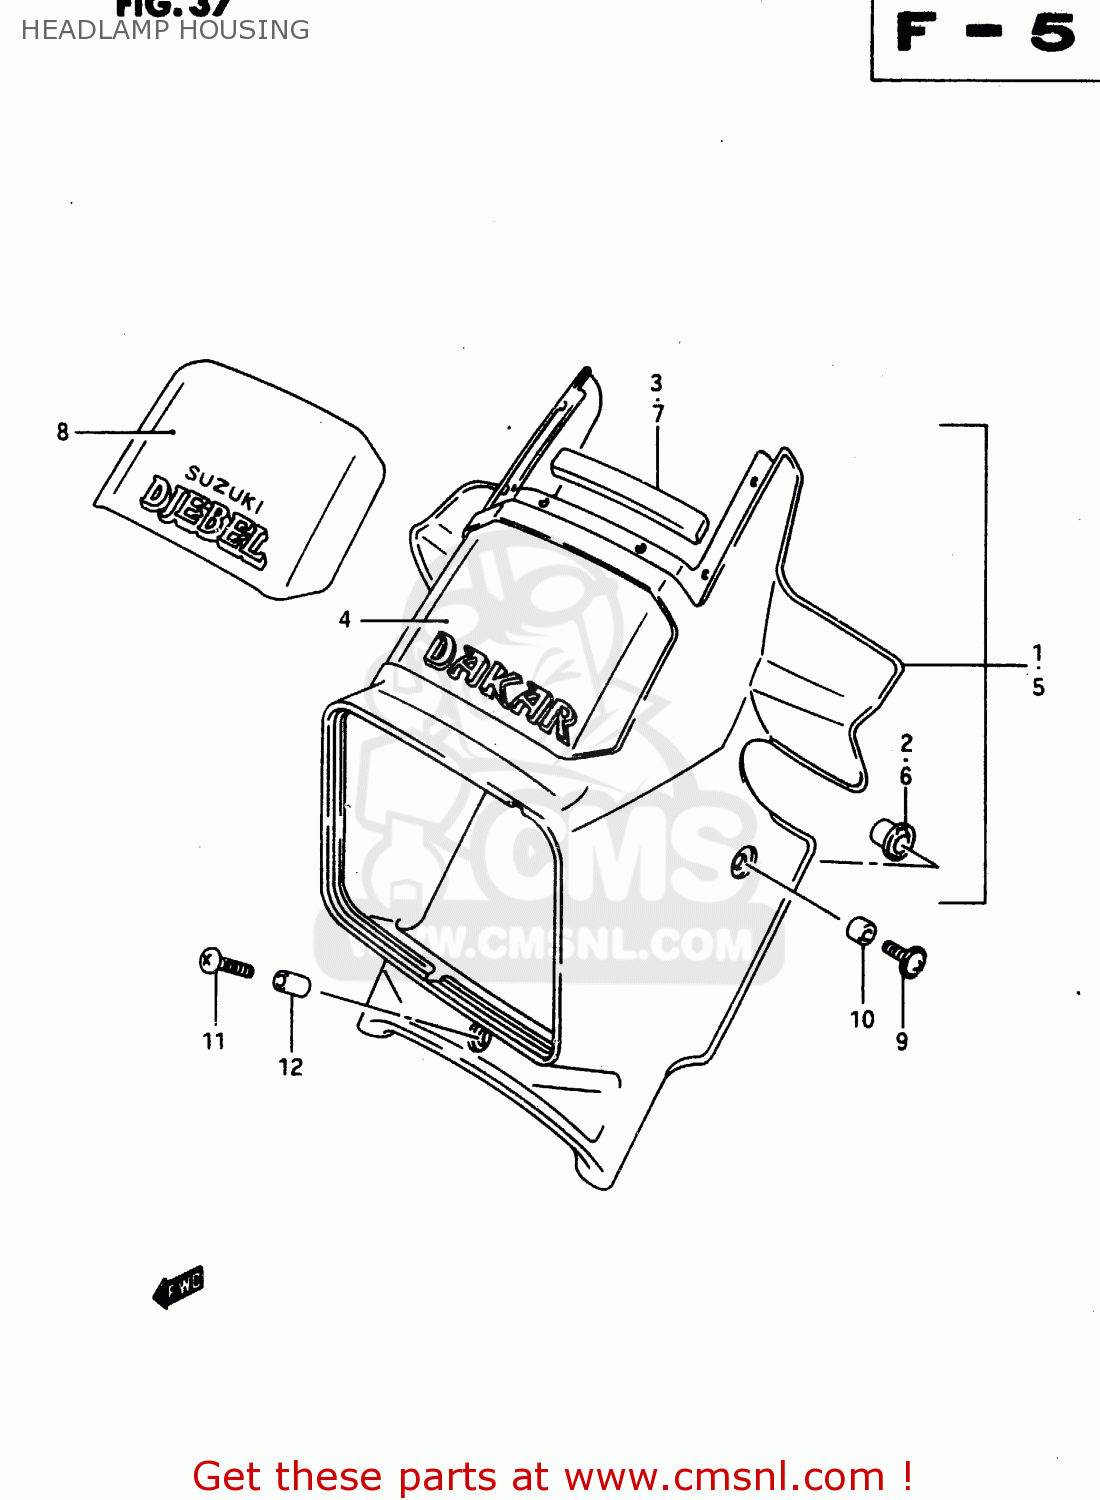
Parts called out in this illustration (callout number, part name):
1	COVER, HEADLAMP (WHITE)
2	BUSH, SIDE (WHITE)
3	CUSHION,HEADLAMP COVER
4	TAPE
5	COVER, HEADLAMP (WHITE)
6	BUSH, SIDE (WHITE)
7	CUSHION,HEADLAMP COVER
8	TAPE
9	SCREW(6X16)
10	SPACER
11	SCREW, LOWER
12	SPACER (6.1X9X31.5)
